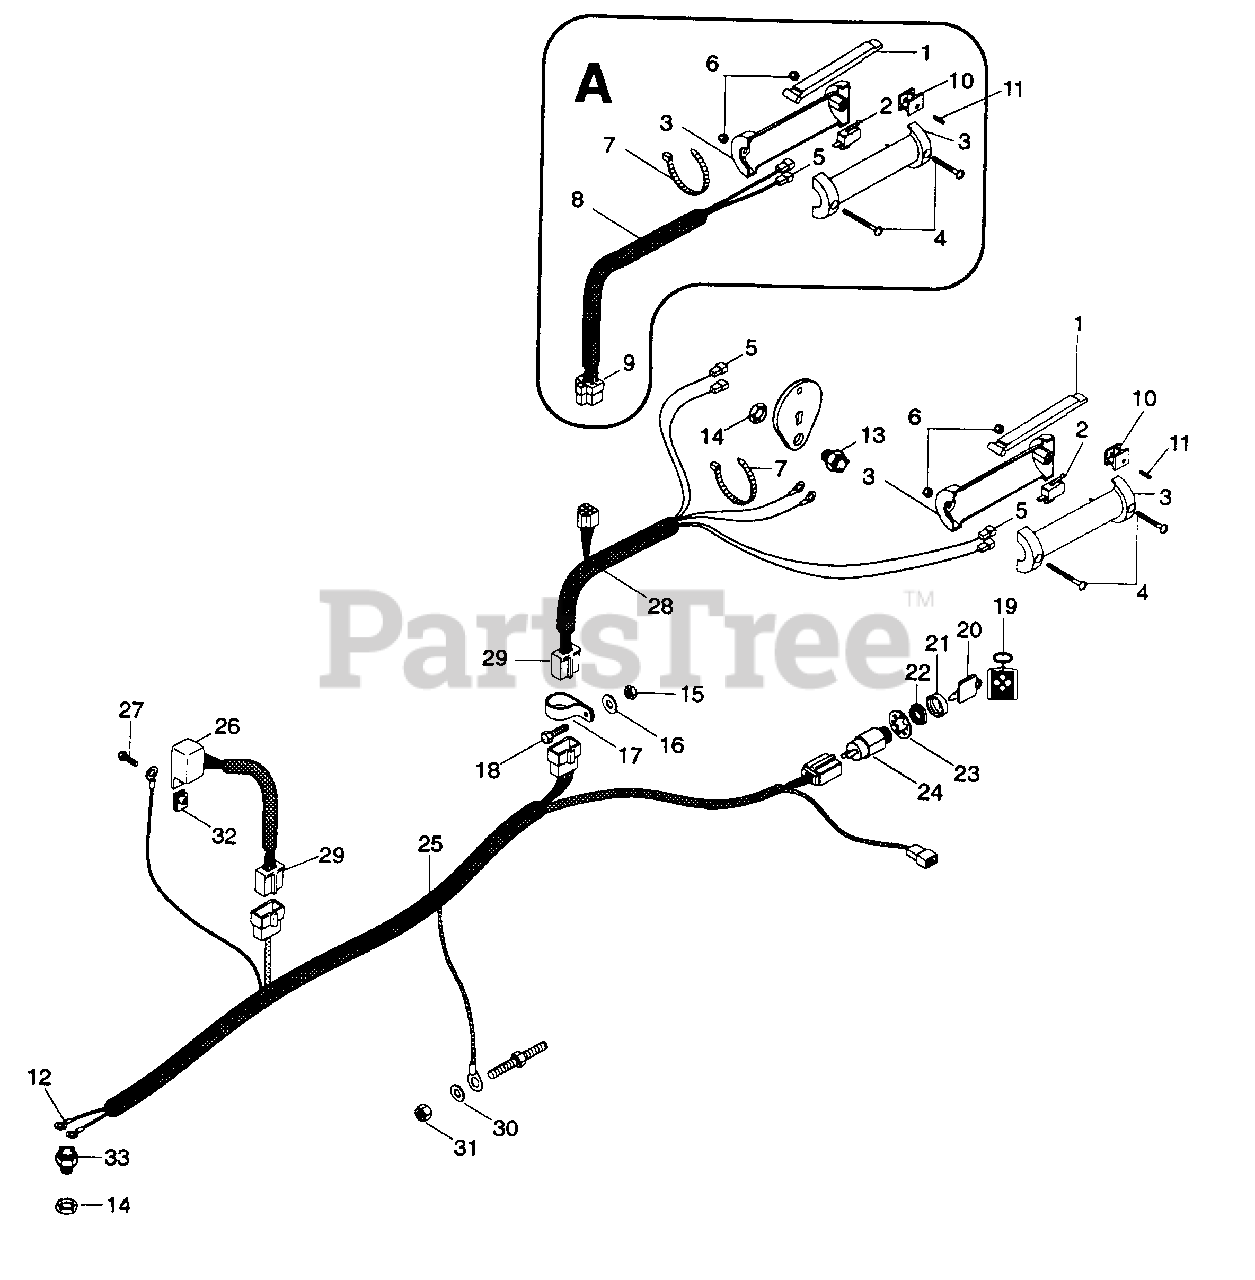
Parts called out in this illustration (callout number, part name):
1	LVR
2	SWITCH
3	HANDLE, L.H. & R.H.
4	SCR-MCH 10-24 X 1.50 PHDCR
5	TERMINAL, FEMALE
6	NUT-LK 10-24 NY PL
7	TIE WRAP, BLACK
8	HMS, STEERING BRAKE
9	CONNECTOR
10	HOLDER SWITCH
11	PIN-ROLL .094 X .750
12	TERMINAL, EYELET
13	SWITCH, INTERLOCK CLOSED
14	NUT-STAMPED .56-18
15	NUT-LK-NYL .250-20 PL
16	WSHR-FL-STL 281 X .62 X .065 PL
17	CABLE CLAMP
18	BLT-HEX .25-20 X .75 PL GR 5
19	KEY CHAIN
20	IGNITION SWITCH KEY
21	CAP-IGNITION SWITCH
22	NUT-PANEL .625-32 GRECO
23	WSHR-LOCK INT .625 X .045 PL
24	SWITCH ASSEMBLY
25	HMS, 8 & 12-HP RECOIL
26	MODULE, INTERLOCK RECOIL
27	BLT-HEX .25-20 X .63
28	HMS, WIRING HANDLE BAR
29	TERMINAL
30	WSHR-FL-STL .469 X .938 X .065
31	NUT-LK-NYL .375-16 PL
32	NUT-SPEED .25-20
33	SWITCH, INTERLOCK OPEN
